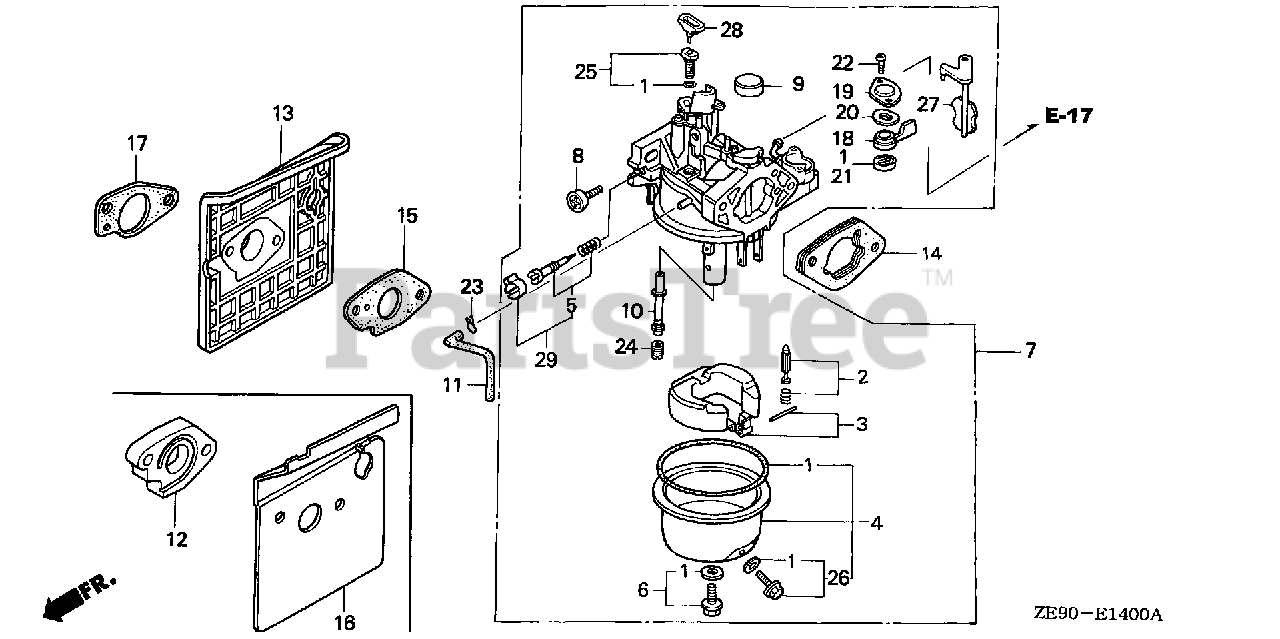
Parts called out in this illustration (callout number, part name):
1	GASKET SET (CARBURETOR NO.)
1	GASKET SET (CARBURETOR NO.) (EXCEPT 16173-001-004)
2	VALVE SET, FLOAT
4	CHAMBER SET, FLOAT
5	SCREW SET, PILOT
6	SCREW SET
7	CARBURETOR ASSY. (BE35A B)
7	CARBURETOR ASSY. (BE35A C)
7	CARBURETOR ASSY. (BE35A D/E)
8	SCREW, THROTTLE STOP
9	CAP, CHOKE DUST
10	NOZZLE, MAIN
11	TUBE, AIR VENT (75MM)
12	INSULATOR, CARBURETOR
14	SPACER, CARBURETOR
16	GASKET, CARBURETOR (NOT AVAILABLE)
17	GASKET, INSULATOR
18	LEVER, PETCOCK
19	PLATE, LEVER SETTING
20	SPRING, PETCOCK LEVER
21	GASKET, PETCOCK (CARBURETOR NO.)
22	SCREW, PAN (3X8)
23	CLIP, TUBE (B8)
24	JET, MAIN (#82)
24	JET, MAIN (#85)
24	JET, MAIN (#88)
25	JET SET, PILOT (#40)
